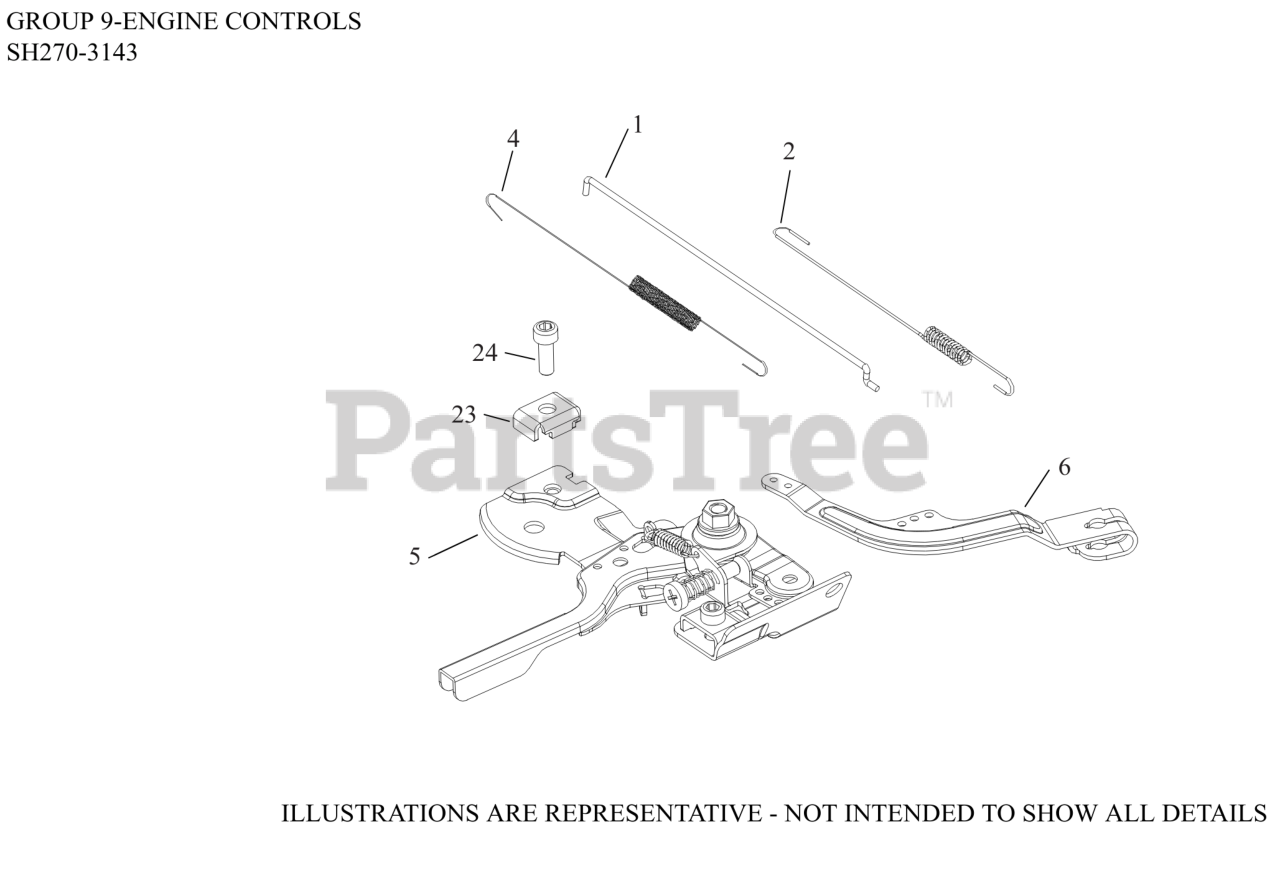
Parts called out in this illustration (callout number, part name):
1	LINKAGE, GOVERNOR-USE 18 079 05-S
2	SPRING, GOVERNOR
4	SPRING, LINKAGE
5	VARIABLE SPD CNTRL ASSY W/O KILL
6	KIT, GOVERNOR LEVER
23	CLAMP, CABLE
